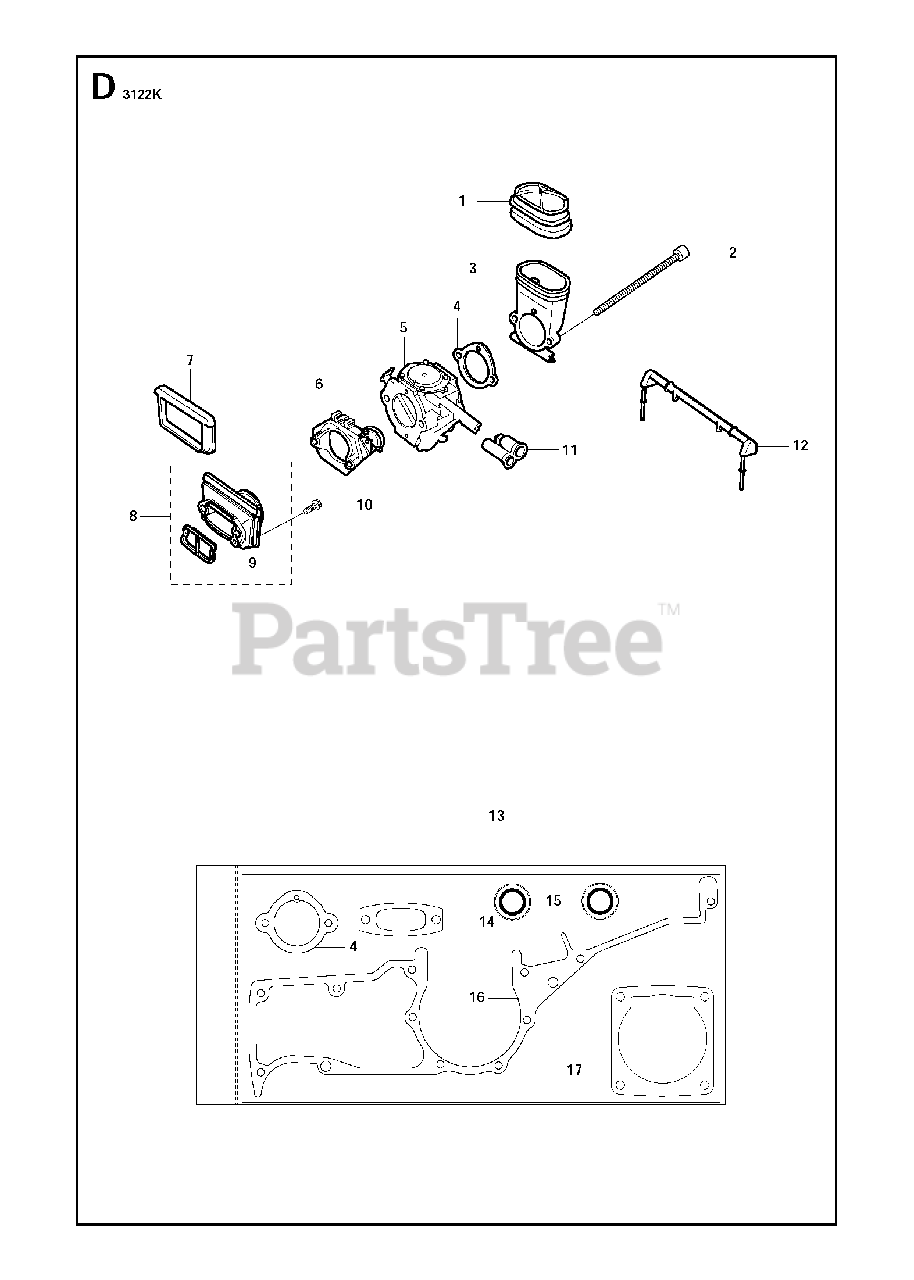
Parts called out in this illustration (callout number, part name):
2	SCREW ITXSCT
4	GASKET
8	FLANGEIncl. 9
10	SCREW ITXSCM
11	CHISEL GUIDE
13	GASKET KITIncl. 4, 14 - 17
15	SEALING RING
